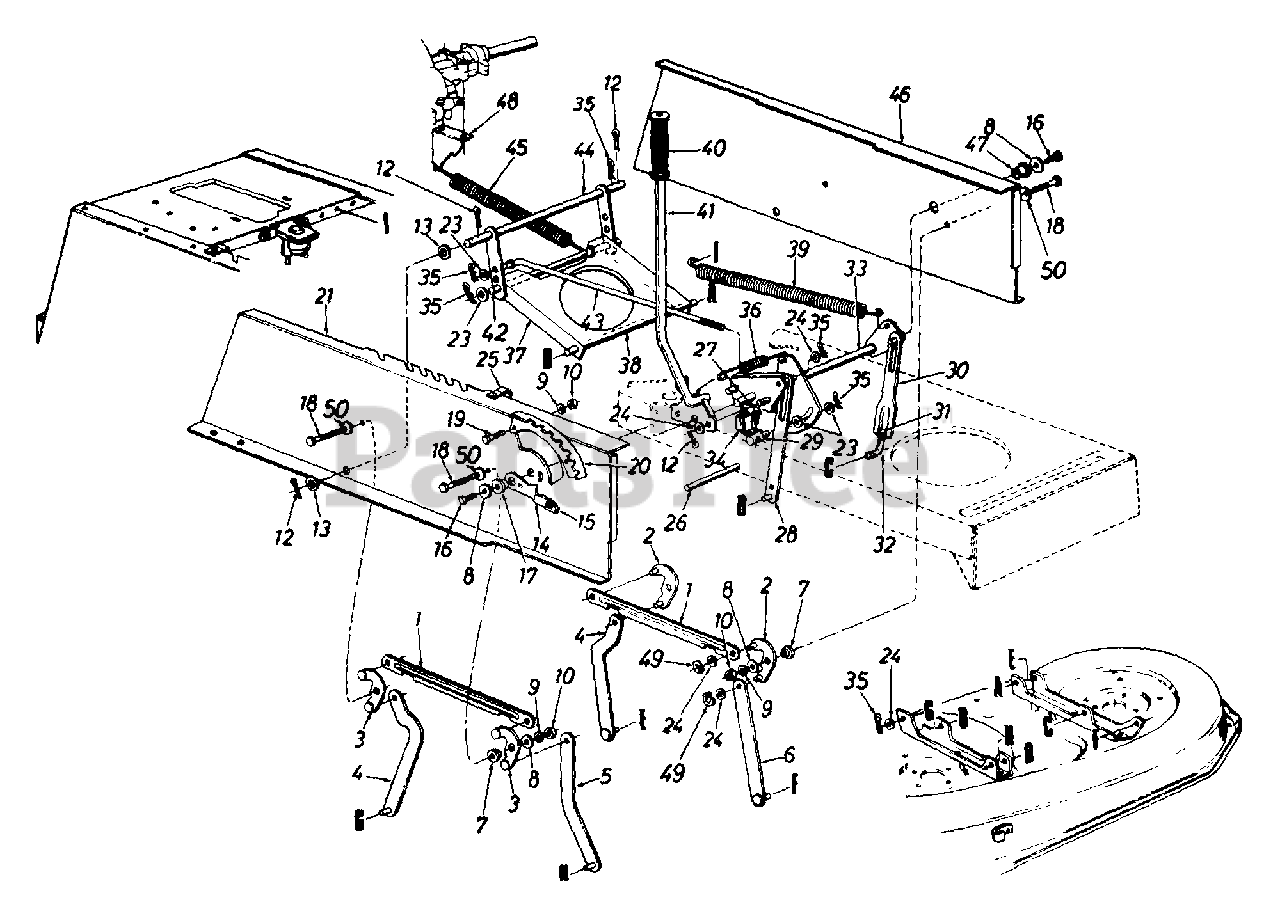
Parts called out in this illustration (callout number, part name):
1	Connecting Rod
2	Pivot Link Ass'y.- L.H. (Uses "E"-Ring)
3	Pivot Link Ass'y.- R.H, (Uses "E"-Ring)
7	Shld. Spacer .318" I.D.
8	Ft-Wash. .344" I.D. x .62" O.D.
9	L-Wash. 5/16" I.D.
10	Hex Nut 5/16-18 Thd.
12	Cotter Pin 1/8" Dia.
13	Fl-Wash. .635" I.D. x 1.0" O.D.
14	Height Adj. Stop Lever Ass'y.
15	Knob
16	Hex Wash. TT-Tap Scr. 5/16-18 x .75" Lg.
17	Flange Brg. .63" I.D.
18	Hex Wash. Hd. Scr. 5/16-18 x .875" Lg.
19	Hex Bolt 5/16-18 x .75" Lg.
20	Index Brkt.
24	Fl-Wash. .531" I.D. x .93" 0.0.
25	Clamp
26	Running Board Rod
27	Hex Wash. Hd. Tap Scr.
31	Hex Nut 1/2-20 Thd. (Gr. 5)
32	Lift Link Adjuster
35	Inter. Cotter Pin 38" Dia.
36	Extension Spring
39	Extension Spring
40	Grip (Lift Handle)
41	Deck Lift Handle Ass'y.
42	Shaft 3/8" Dia. x 9.34" Lg.
43	Disengagement Rod
44	Stabilizer Shaft Ass'y.
45	Extension Spring 7.58" Lg.
46	Upper Frame - L.H.
47	Flange Brg. .632" I.D.
48	Spring Retainer Brkt.
49	"E"-Ring
50	Bell-Wash. .325" I.D.
